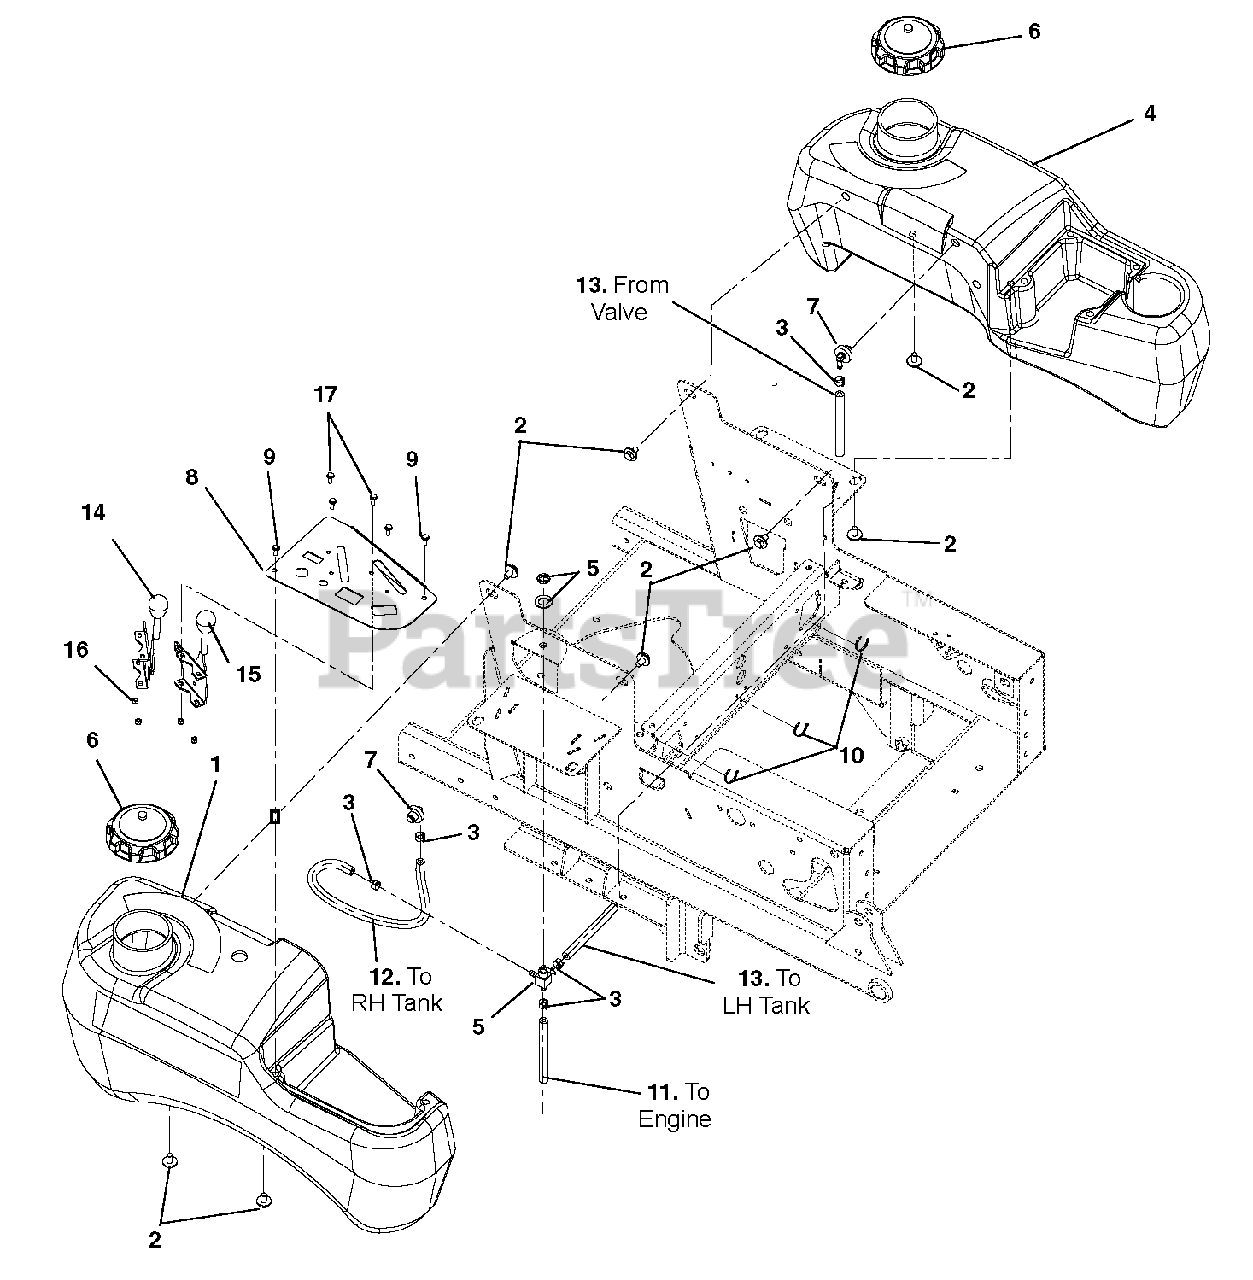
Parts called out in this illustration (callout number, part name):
1	TANK,RH FUEL,100I
2	BOLT, SEMS .31-18 X .62
3	CLAMP, FUEL LINE
4	TANK,LH FUEL,100I
5	VALVE, FUEL
6	CAP, FUEL
7	ASS'Y,MEDIUM TANK FUEL PICK-UP
8	PT100 CONTROL PANEL - BLACK
9	SCR-MCH 10-24X.50 HWHSTAINLESS
10	CABLE TIE LG 5-1/2
11	HOSE, .25 LOW-PERM BULK GAS
12	HOSE, .25 LOW-PERM BULK GAS
13	HOSE, .25 LOW-PERM BULK GAS
14	CABLE, PT 100 CHOKE CONTROL
15	CABLE, PT100 THROTTLE CONTROL
16	@NUT-LK-NYL 10-24 W/INSRT YWZC
17	@SCR-MCH 10-24X.50 HWH YWZC
